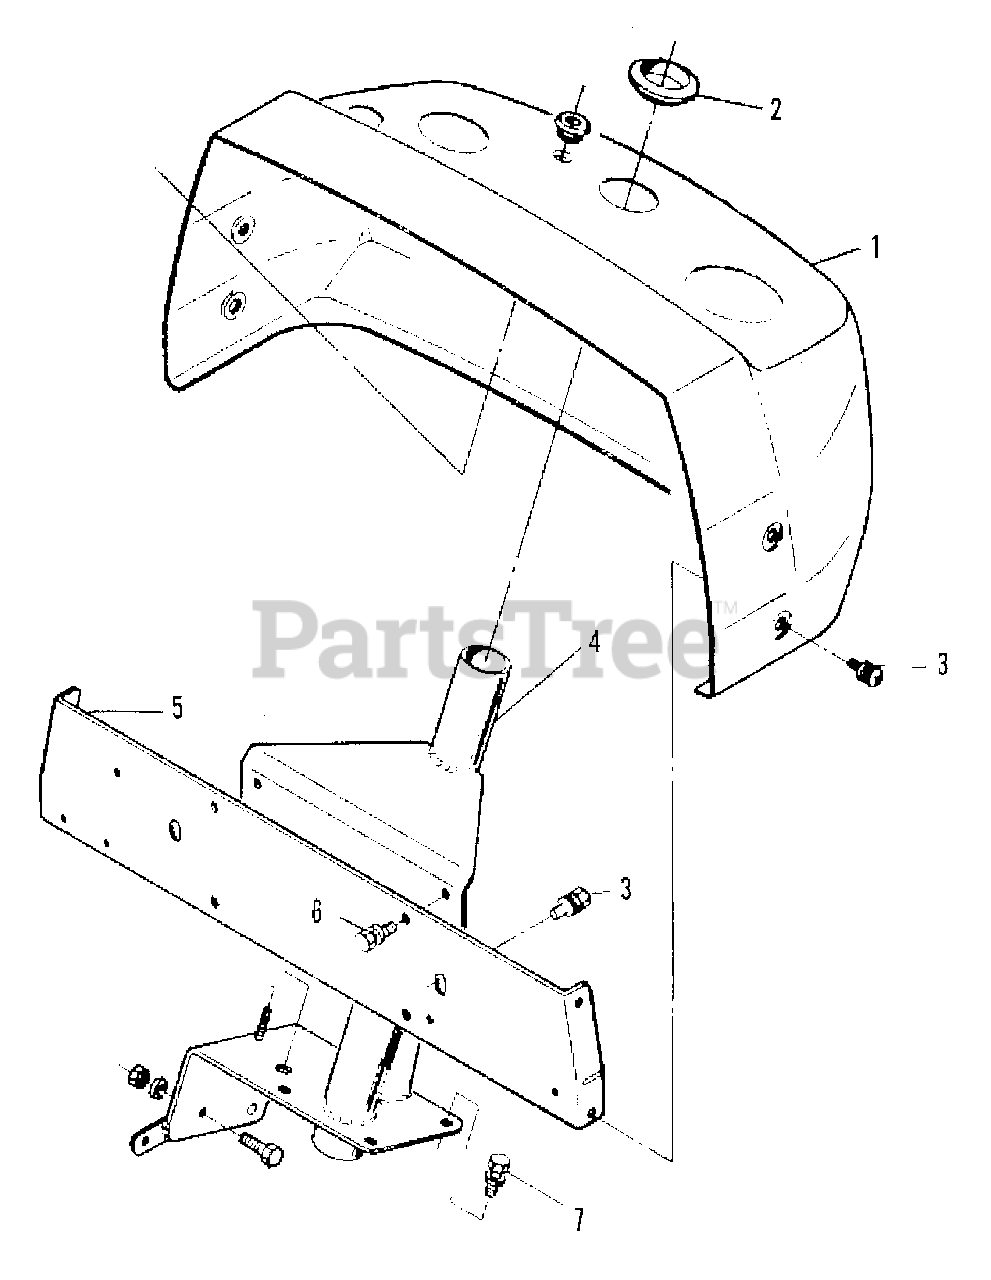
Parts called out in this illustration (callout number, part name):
1	INSTRUMENT PANEL
4	SUPPORT, steering wheel
5	BRACKET, protector
6	CAPSCREW, M8 x 20
7	CAPSCREW, M10 x 20
